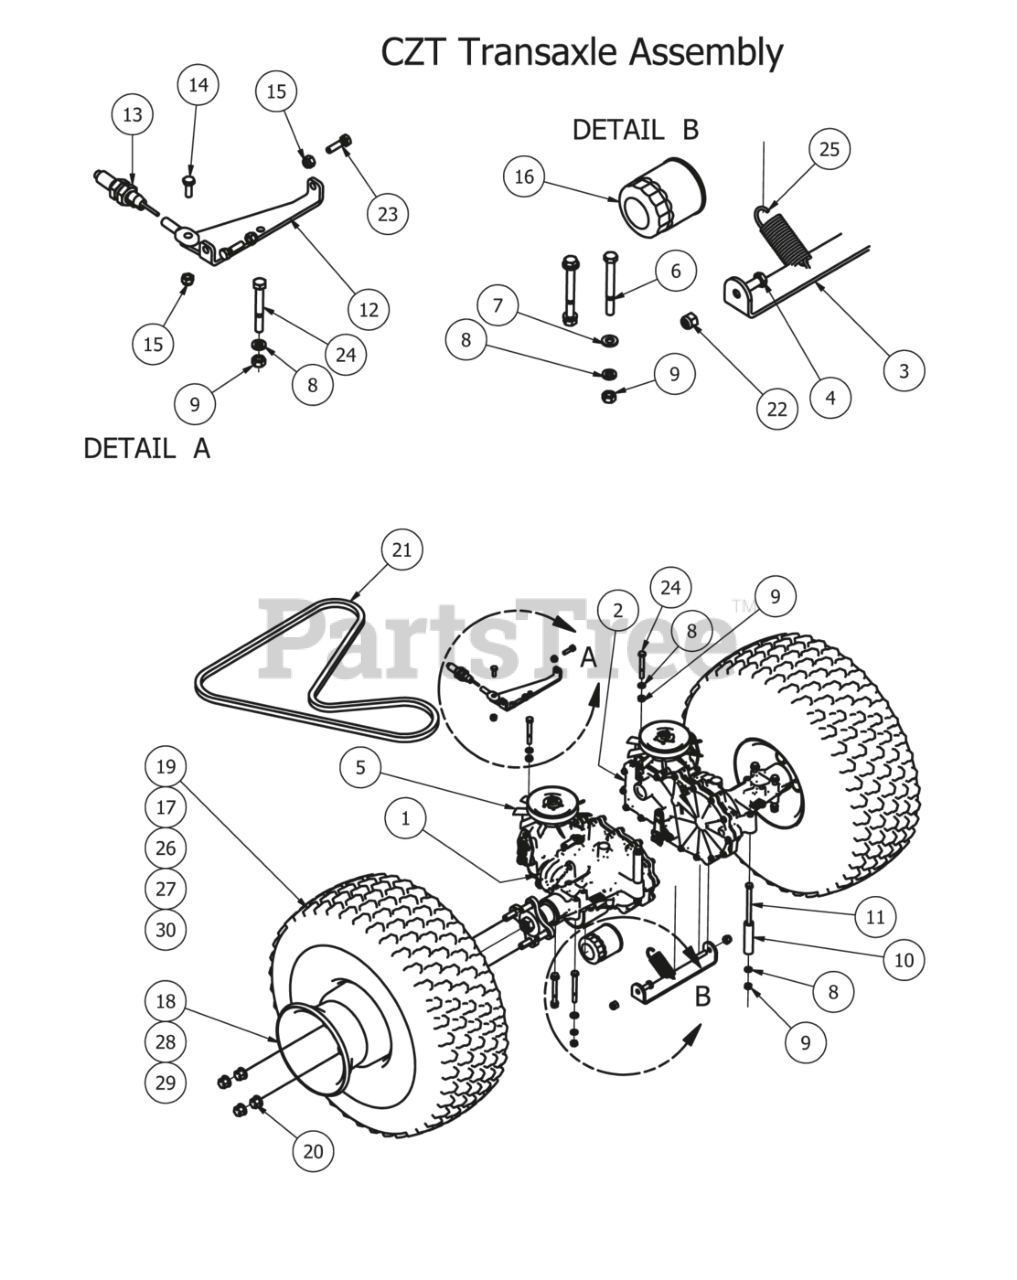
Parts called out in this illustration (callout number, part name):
1	3400 IZT for CZT -Left
2	3400 IZT for CZT - Right
3	Crossover Bar for ZT
4	3/8" x2" Hex Bolt
5	Fan/Pulley kit For CZT
6	5/16" x 3" Hex Bolt
7	5/16" Flat Washer
8	5/16" Lock Washer
10	3 1/4" Spacer
11	5/16" x 6" Bolt
12	ZT Crossover Brake Bracket
13	Short Brake Cable
14	1/4" x 3/4" Hex Bolt
15	1/4" Nylock Nut
16	Transaxle Hydro Filter
17	Tire 23 X 10.50 -12 Assembly W/Negative Offset Wheel (60" Only Deck)
18	( Wheel Only 60" Deck) 12 Orange Wheel
19	23 x 10.50 Tire only (50" & 60" Decks)
20	Acorn Lug Nut
22	3/8 Nylock Nut
23	Hex Bolt - UNC (Regular Thread - Inch)
24	5/16" x 2 1/2" Bolt
26	23x 10.5-12 Tire & Wheel Assembly (50" Only) Deck
27	23 x 8.50 - 12 Tire & Wheel Assembly (42" Only) Deck
28	(Wheel Only 50" Deck) 12 Orange Wheel - 48" and Pup Models
29	(Wheel Only 42" Deck) Wheel 23x8.50
30	23 x 8.50-12 Tire Only (42" Deck)
